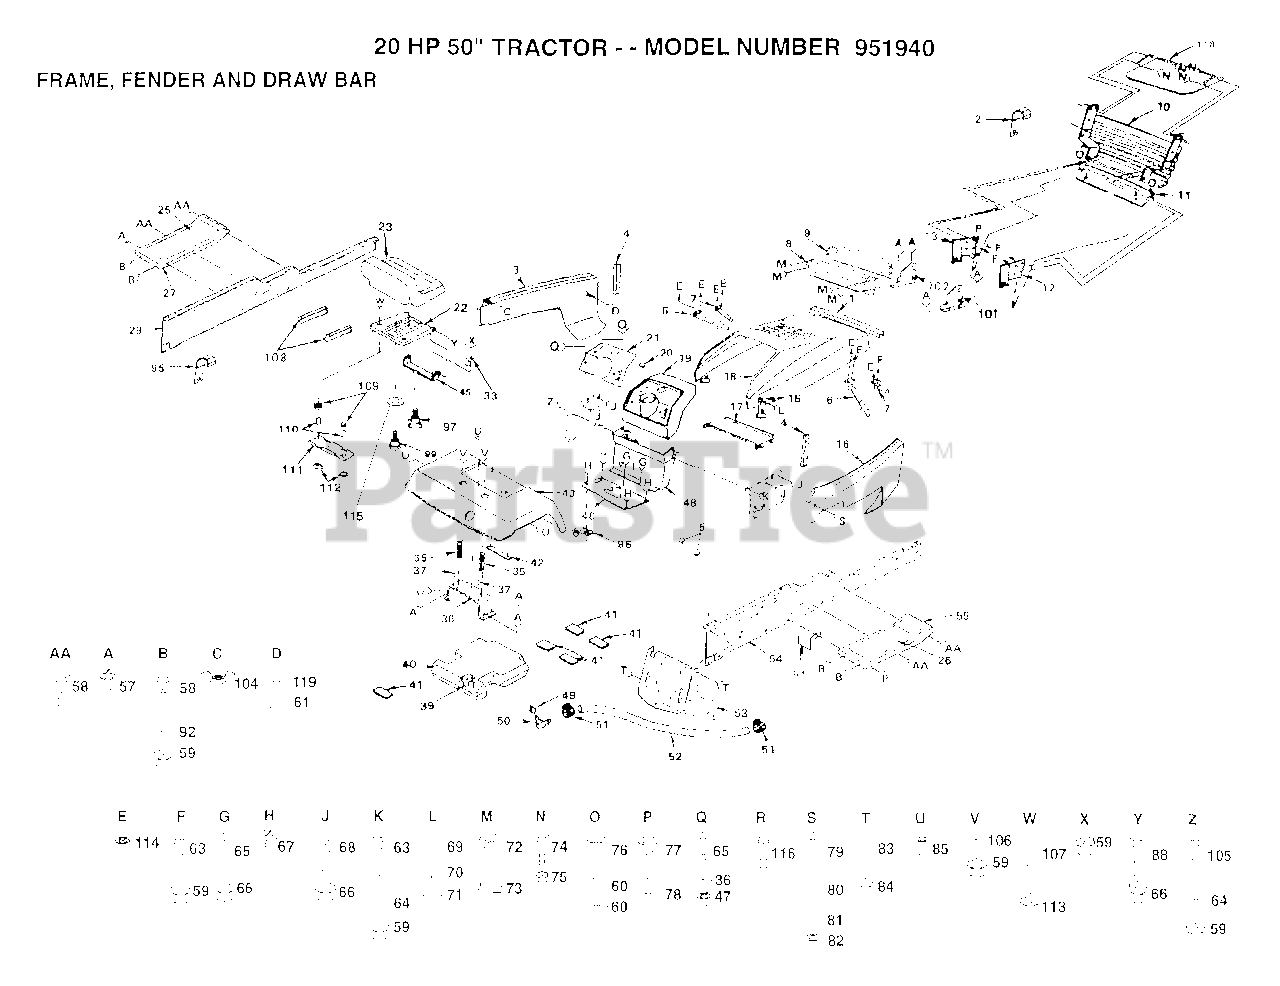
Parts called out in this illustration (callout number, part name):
1	FOAM STRIP T
4	FOAM STRIP T
5	CAP SPRING
9	LENS LT
12	SUPPORT RH YTH
13	SUPPORT LH YTH
15	HOOD LATCH T
16	"PANEL,SIDE RH "
20	PLUG-DASH T
26	FOOTREST PAD
33	CLIP T
35	SPRING COMPRESSIO
36	WASHER
37	NUT-PUSH YT
41	PAD-SPACER LT
43	FENDER
46	SADDLE.6SP.GT
48	DASH ASSEMBLY
49	BUSHING OUTLET T
50	FUEL TANK STEM GT
51	HOSE CLAMP
57	SCREW
60	WASHER PM
63	BOLT
64	WASHER
65	SCREW
67	SCREW
68	BOLT
69	SCREW
70	LOCKWASHER
71	WELDNUT
73	"""J"" FASTENER LT"
76	SCREW
77	SCREW
78	WASHER
79	SCREW
80	SPACER LT
81	WASHER
83	BOLT
84	NUT GTV
85	SCREW LT
91	BELT RETAINER GT
92	WASHER
97	"KNOB 1/2"" YT"
99	"BOLT,SHOULDER"
101	SUPPORT RH YTH
102	SUPPORT LH YTH
106	WASHER
108	STRIP FORM
109	SPRING COMPRESSED
110	SPACER SPLIT
111	BRKT SWITCH
112	BUSHING
114	NUT
115	WASHER
116	SCREW GTV
118	"SHIELD,HEAT"
119	WASHER
